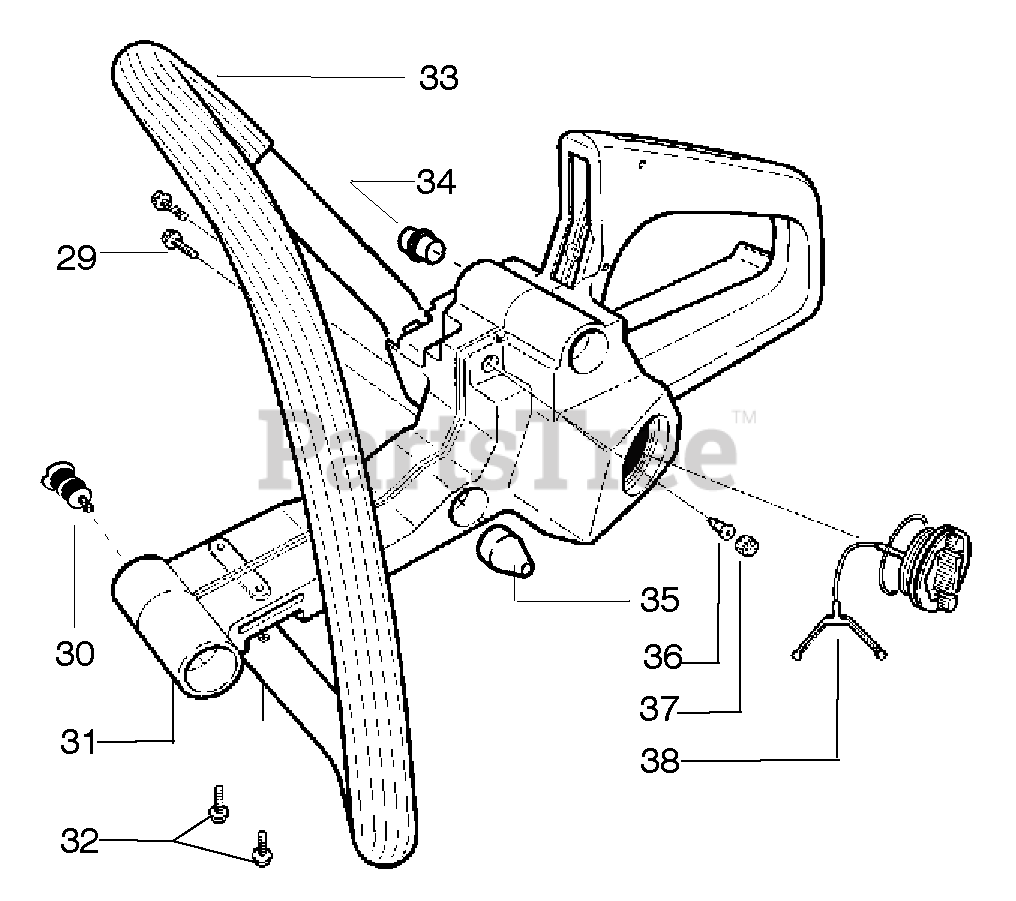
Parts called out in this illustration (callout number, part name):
31	Assy. -Tank/Handle
33	Handle-Front
34	Isolator - Limiter
35	Isolator Bumper
36	Valve - Check
37	Plug - Vent
38	Kit-Fuel Cap-Assy
